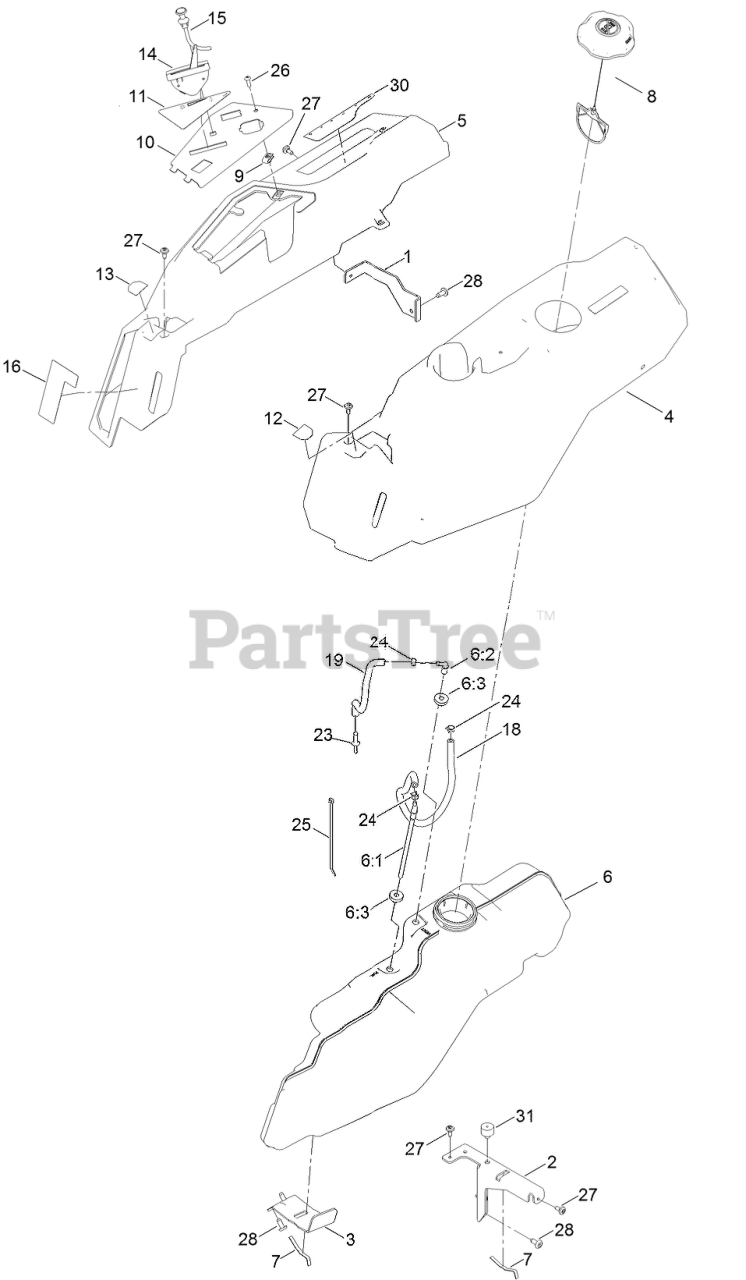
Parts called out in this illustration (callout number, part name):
1	BRACKET-POD
2	SUPPORT-POD, LH
3	SUPPORT-TANK, FUEL
4	POD-LH
5	POD-RH, MYRIDE
6	FUEL TANK ASM
6:1	CONNECTOR-ELBOW, 90 DEG
6:2	FITTING-PLASTIC
6:3	BUSHING
7	SPRING
8	CAP-FUEL, RATCHETING
10	PANEL - CONTROL
11	DECAL-PANEL, CONTROL
12	DECAL-CONTROL LEVER, LH
13	DECAL-CONTROL LEVER, RH
14	CABLE-THROTTLE
15	CABLE-CHOKE
16	DECAL-SMART SPEED
18	HOSE-FUEL
19	HOSE-FUEL
23	ADAPTOR-ORIFICE
24	CLAMP-HOSE
25	TIE-CABLE
26	SCREW-PRH
27	SCREW-SHOULDER
30	DECAL-ADJUSTMENT
31	BUMPER-GROMMET
